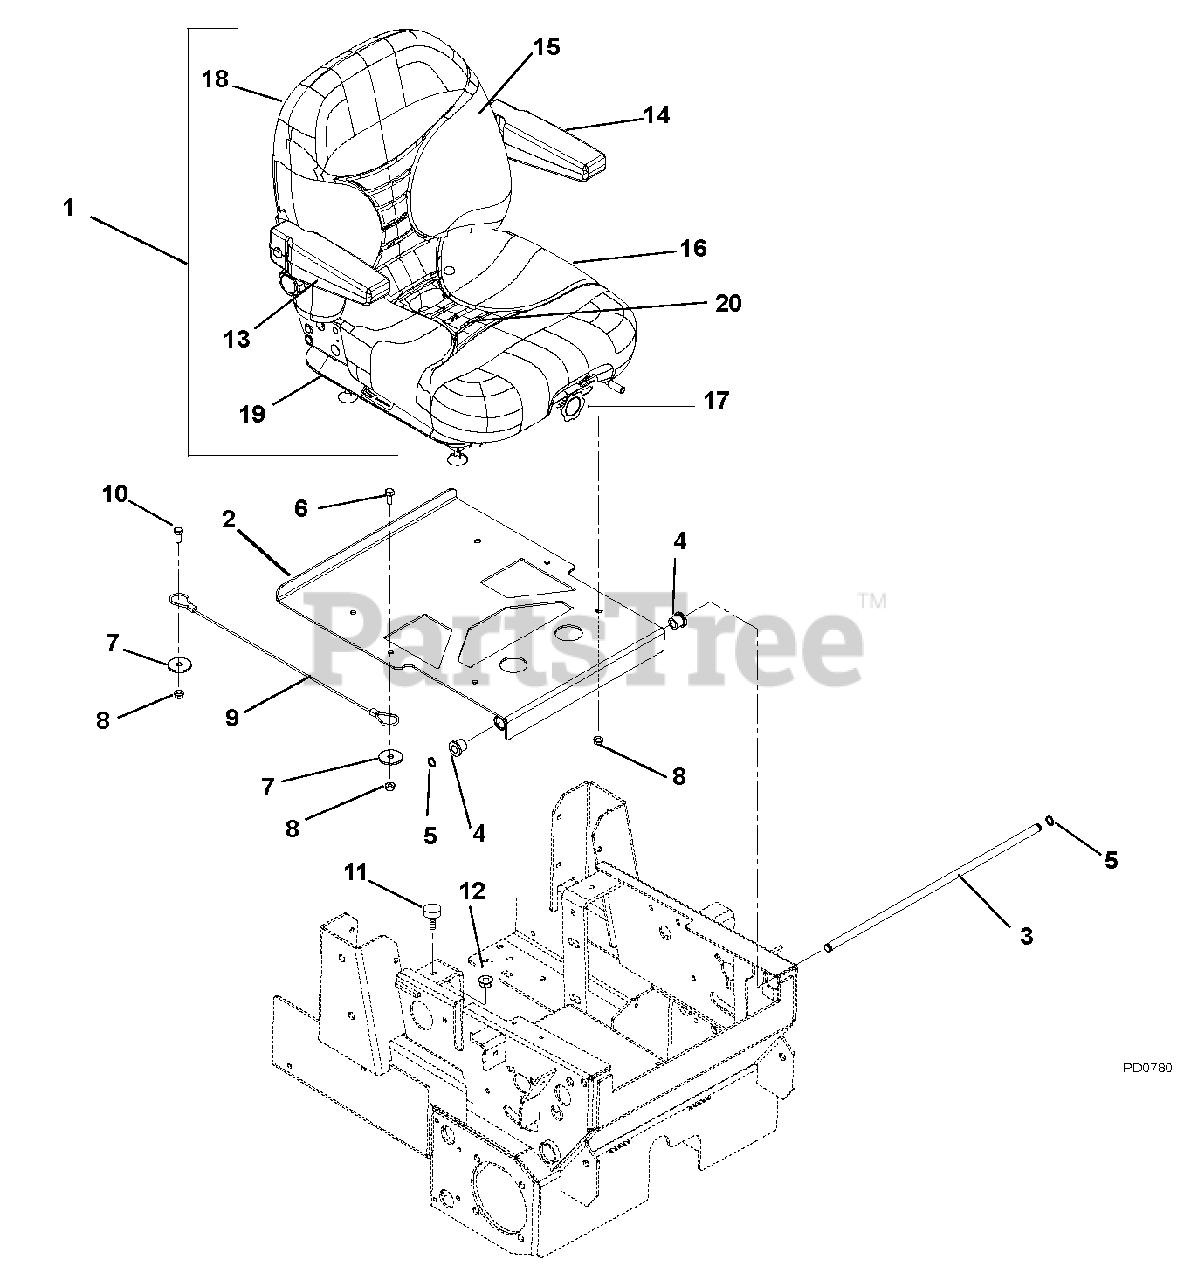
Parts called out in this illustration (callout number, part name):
1	Seat, Suspension, Light Grey (Includes items 13 – 20)
2	Plate, Seat Pivot
3	Rod, Seat Pivot (Outfront)
4	Bushing, Flange .515 x .750 x .745 x 1.00 Nylon
5	Ring, Retaining External .500 x .050
6	Bolt, Hex .31-18 x .75 Grade 5
7	Washer, Flat Steel .344 x 1.125 x .135
8	Nut, Nyloc Flange .31-18
9	Cable, Seat Prop
10	Bolt, Round Head Square Neck .31-18 x 1.00 Grade 5
11	Bumper, Rubber
12	Nut, Spin Lock Flange .312-18
13	Kit, Right Hand Armrest Assembly
14	Kit, Left Hand Armrest Assembly
15	Kit, Back Cushion, Light Grey
16	Kit, Seat Cushion, Light Grey
17	Kit, Seat Knobs
18	Kit, Seat Back
19	Kit, Seat Slides
20	Kit, Seat Spring and Saddle
